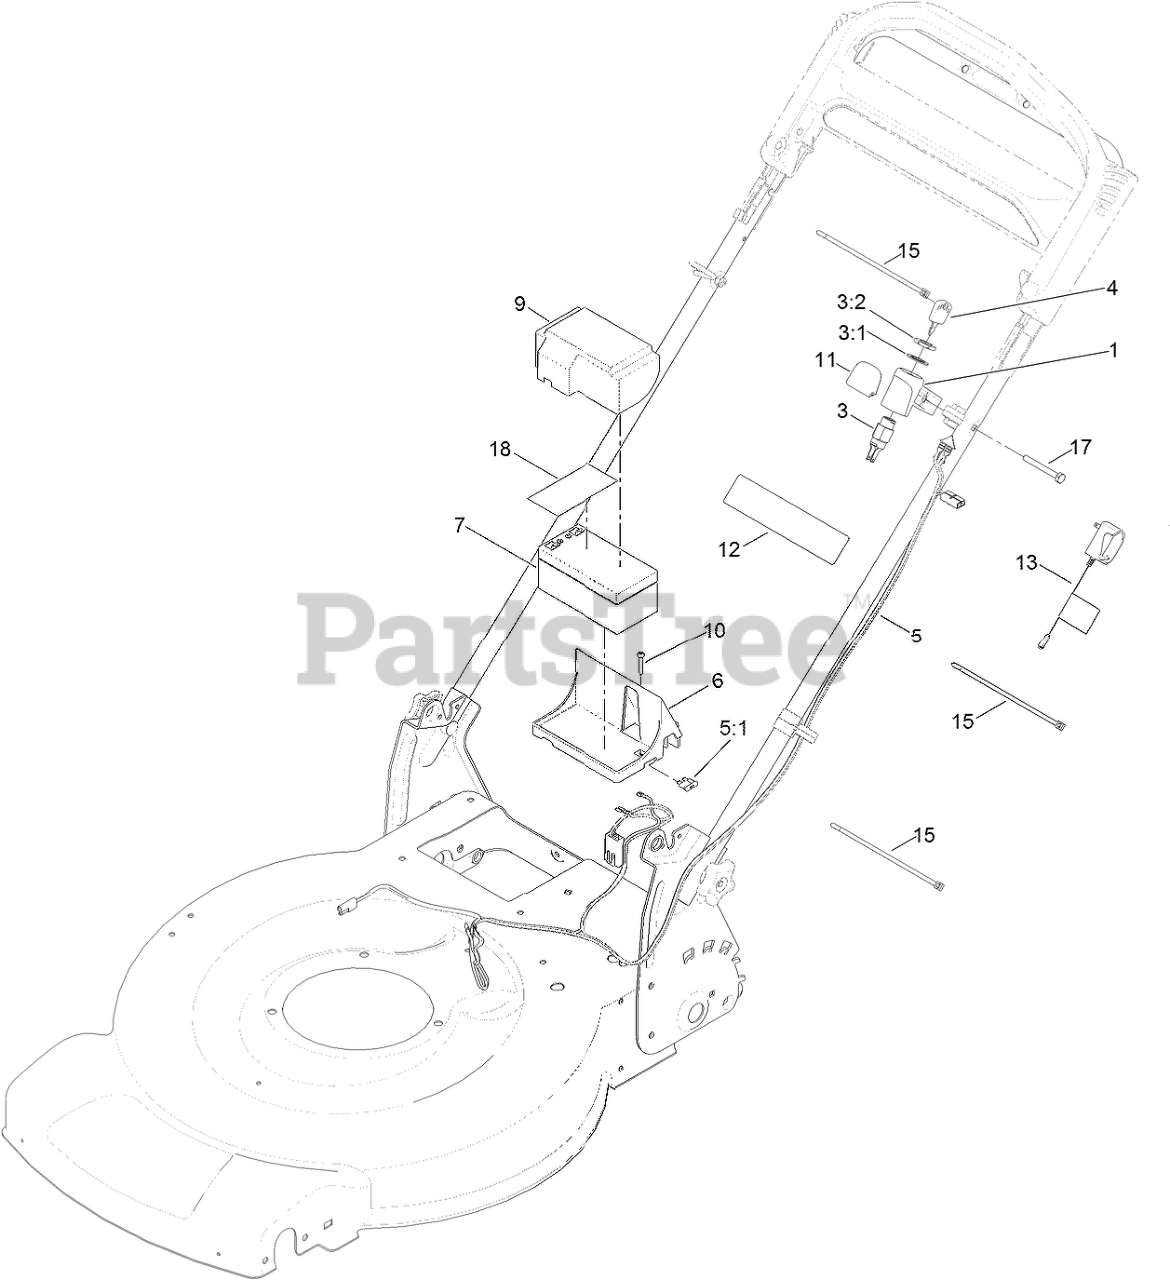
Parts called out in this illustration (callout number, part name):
1	MOUNT-SWITCH
3	STARTER SWITCH ASM
3:1	WASHER-TOOTH, INTERNAL
3:2	NUT-HH
5	HARNESS-WIRE
5:1	FUSE-40 AMP
6	TRAY-BATTERY
7	BATTERY-WET
9	COVER-BATTERY
10	SCREW-PPH, PLASTITE
11	DECAL-ELECTRIC START
12	DECAL-WARNING
13	CHARGER-CE
15	TIE-CABLE
17	SCREW-HH
18	DECAL-TERMINAL, BATTERY
